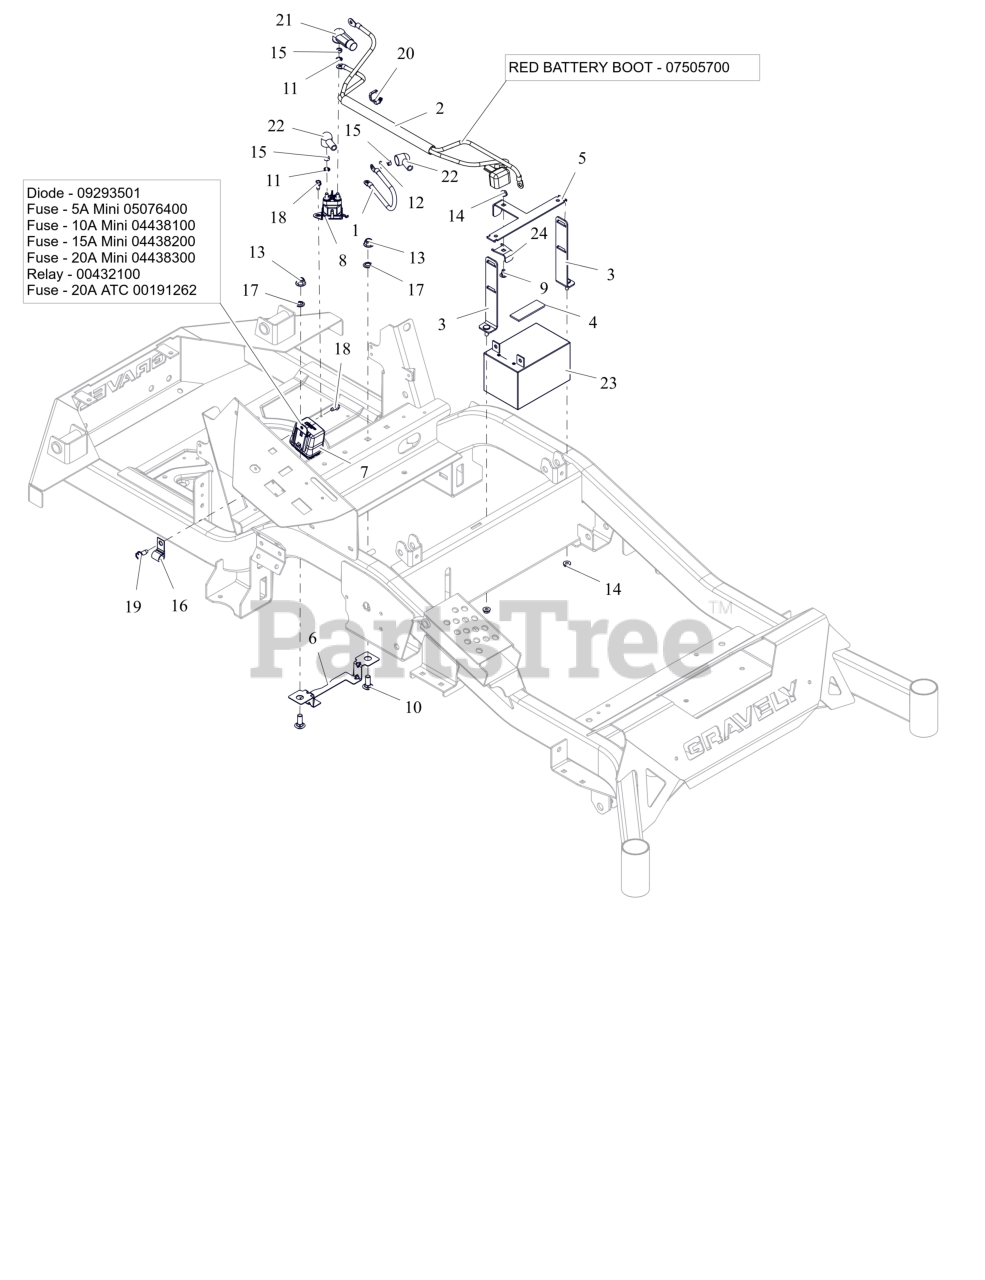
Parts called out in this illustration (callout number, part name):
1	CABLE, POS W/(2)1/4 RING 9.0LG
2	HARNESS, BATTERY HD
2	INSULATOR
3	WMT,BATTERY MOUNT HOLD DOWN
4	PAD,RBR 1.0"X3.0" W/ADHESIVE
5	BRKT, BATTERY TIE DOWN
6	GUARD, ELECTRICAL HARNESS
7	HARNESS, WIRE
7	RELAY,MICRO5 TERML W/RESISTOR
7	DIODE, CONNECTOR SHELL
7	FUSE, 5 AMP MINI-ATC
7	FUSE,10 AMP MINI-ATC
7	FUSE,15 AMP MINI-ATC
7	FUSE,20 AMP MINI ATC
7	FUSE, 20 AMP BLADE S/O
8	SOLENOID, STARTER (SEALED)
9	BLT, RHSN .25-20X.500 G5 ZCC
10	BLT, RHSN .38-16X1.00 G5 ZCC
11	WSHR,LK-EXT.262X.502X.026 ZCC
12	WSHR,LK-REG .312X.078 ZCC
13	NUT,NYL-FLG .38-16 GF ZCC
14	NUT-LK-TOP-FLG .250-20 GF ZCC
15	NUT-STD M6-1.0 ZCC
17	NUT-PUSH .38 DIA. PAL ZINC
18	SCR-TAP .25-20X.50 HWH ZCC
19	SCR,TAP .312-18X.75 HWH TR ZCC
20	CABLE TIE W/ TREE (.25 HOLE)
21	BOOT, .65ID POS
22	BOOT, EYELET TERMINAL
23	BATTERY, 12V 12A -190CCA
24	BRKT, BATTERY HOLD
